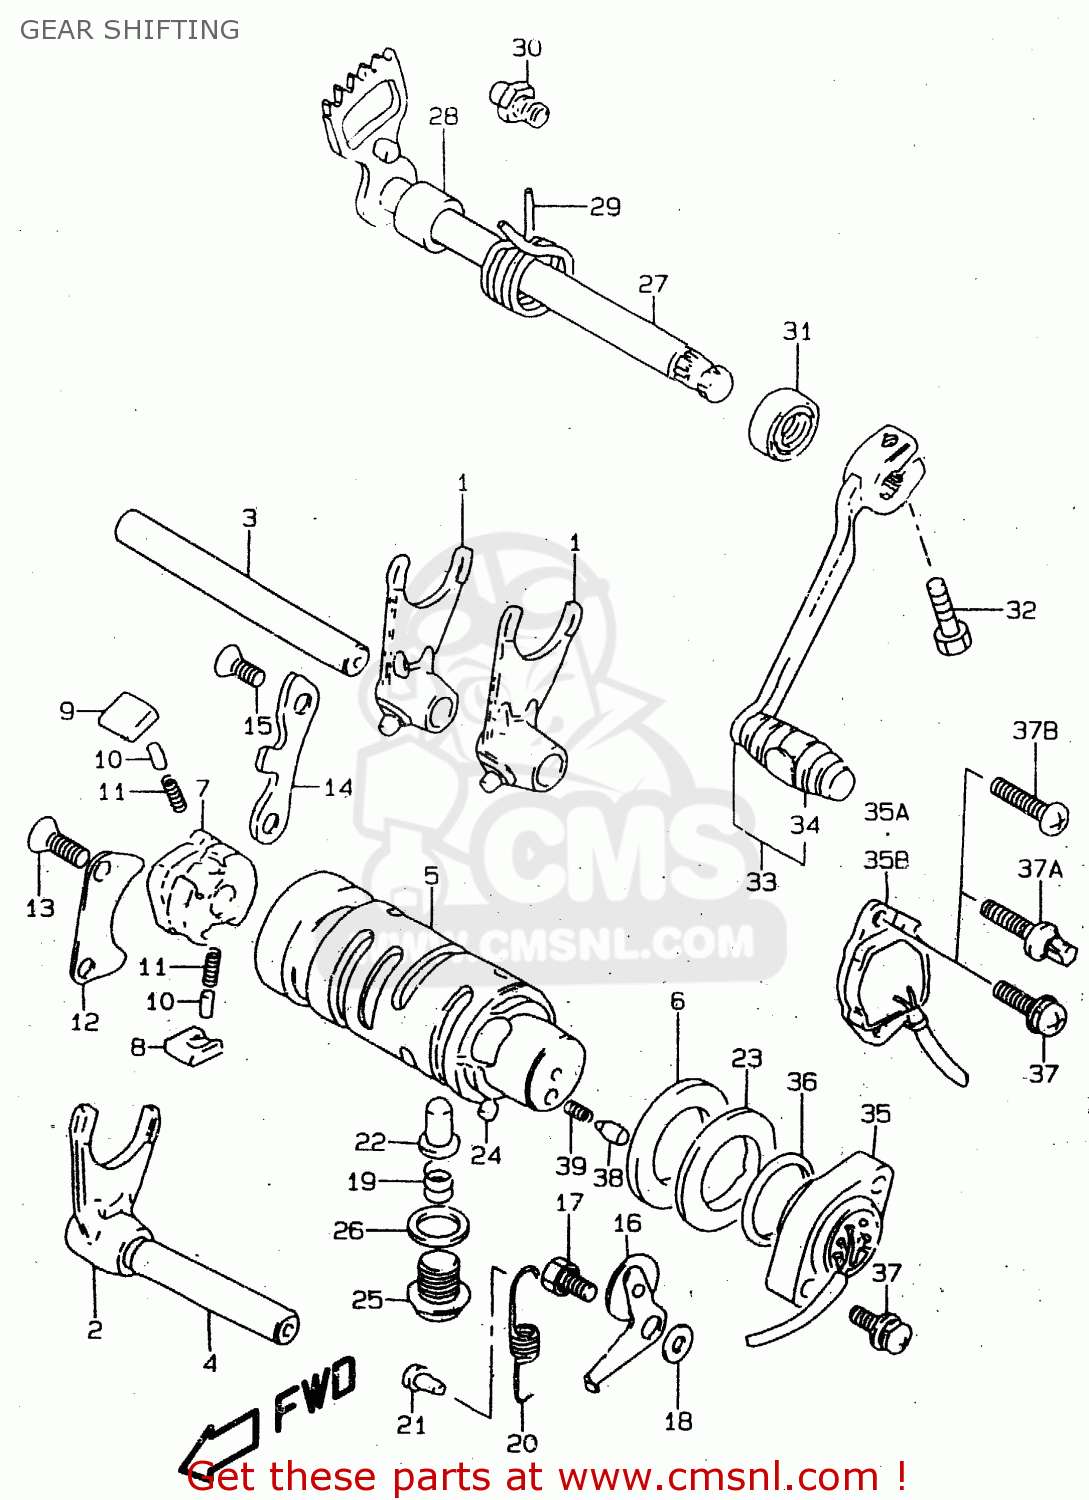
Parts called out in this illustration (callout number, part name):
1	FORK,GEAR SHIFT NO.2
2	FORK,GEAR SHIFT NO.3
3	SHAFT,GEAR SHIFT FORK(L:109)
4	SHAFT,GEAR SHIFT FORK
5	CAM,GEAR SHIFT
6	SHIM(25X40X1)
7	GEAR,GEAR SHIFT CAM DRIVEN
8	PAWL,GEAR SHIFT NO.1
9	PAWL,GEAR SHIFT NO.2
10	PIN(5X8)
11	SPRING
12	LIFTER,GEAR SHIFT POLE
13	SCREW
14	GUIDE,GEAR SHIFT CAM
15	SCREW
16	STOPPER,GEAR SHIFT CAM
17	BOLT(6X14.6)
18	WASHER
19	SPRING
20	SPRING
21	RIVET
22	STOPPER,GEAR SHIFT CAM NO.2
23	PLATE,GEAR SHIFT CAM STOPPER
24	PIN
25	PLUG(14X12)
26	GASKET(13.8X18.8X4.8) (NAS)
27	SHAFT,GEAR SHIFT
28	SPACER(12X20X15.3)
29	SPRING
30	STOPPER,GEAR SHIFT CAM
31	OIL SEAL
32	BOLT
33	LEVER ASSY,GEAR SHIFT
34	RUBBER,GEAR SHIFT PEDAL
35	BASE ASSY,NEUTRAL SW TERMINAL
35A	BASE ASSY,GEAR SHIFT TERMINAL
35B	BASE ASSY,GEAR SHIFT TERMINAL
36	O-RING (D:2.4 ID:26.2)
37	SCREW
37A	BOLT
37B	SCREW 5X20
38	PIN(5X15.5)
39	SPRING
